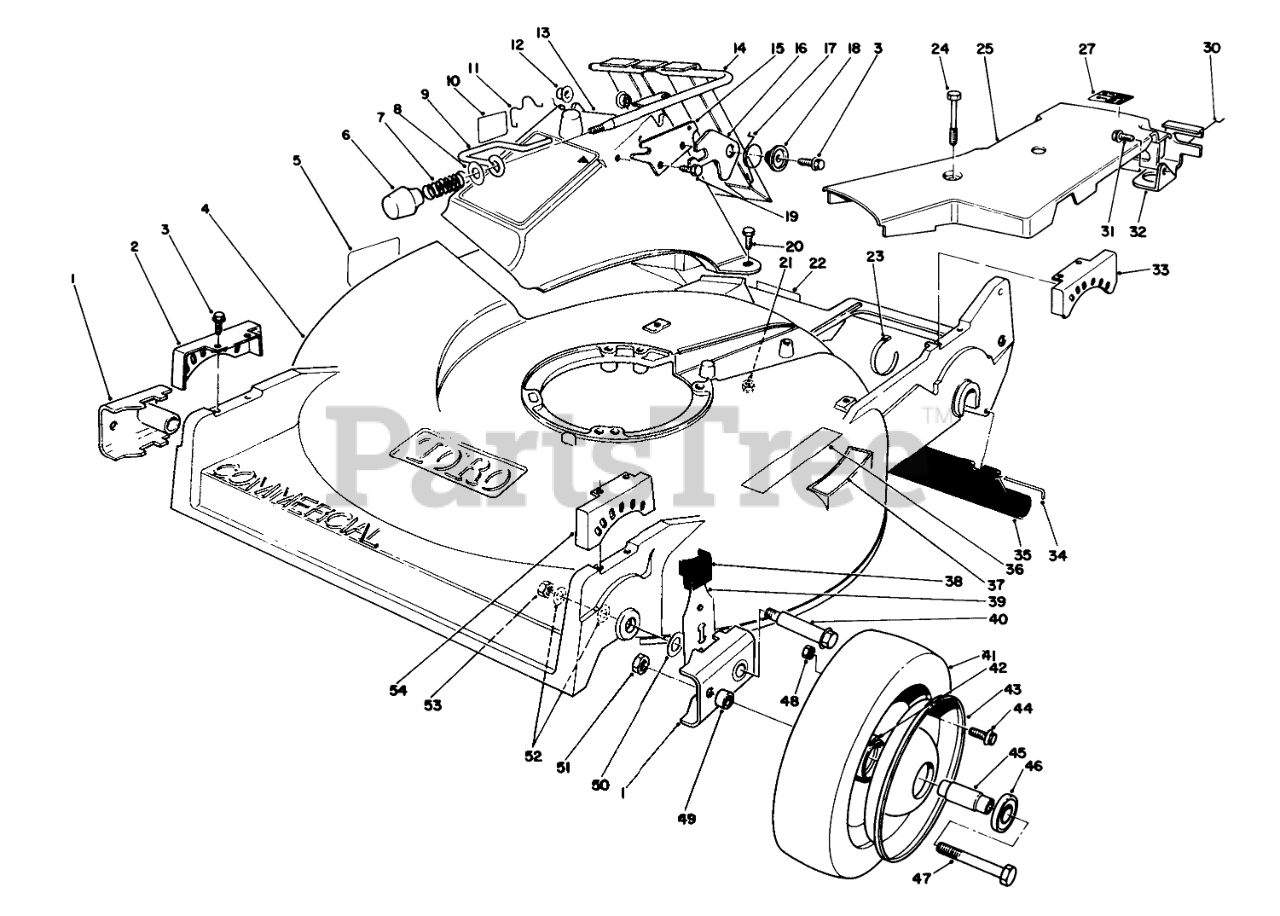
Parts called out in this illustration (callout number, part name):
1	ARM-PIVOT, FRONT
2	QUADRANT-FRONT, RH
3	SCREW-HWHTF
4	Housing-Commercial (Incl. Ref. #5 & 35)
5	Decal Danger
7	COMPRESSION SPRING
8	WASHER-FLAT
9	DOOR LATCH
10	DECAL - DANGER
11	DOOR RETAINER
12	BUSHING-NYLON
13	DISCHARGE CHUTE B
14	DOOR & HANDLE WA
15	DOOR LATCH PLATE
16	SAFETY LATCH
17	TORSION SPRING
18	DOOR SPACER
19	SCREW-HWH
20	SCREW-HH
21	NUT-LOCK, NI
22	Decal
23	TIE-CABLE
24	SCREW-HHFTF
25	Cover-Belt
27	Label-Grease
30	RETAINER-CABLE
31	SCREW-HWHTF
32	Bracket-Traction Adj.
33	QUADRANT-REAR, LH
34	ROD-SHIELD
35	SHIELD-TRAILING
36	Decal-Danger
37	DECAL - STEP PAD INT'L
38	KNOB-ARM
39	FRONT SPRING ARM ASM
40	WHEEL BOLT
42	HUB-BEARING
43	Wheel-Half
44	SCREW-HHF
45	SPACER-BEARING
46	BEARING-WHEEL
47	SCREW-HH
48	NUT-LOCK, NI
49	SPACER-WHEEL
50	WASHER-THRUST
51	NUT-LOCK, CONE
52	WASHER
53	Nut
54	QUADRANT-FRONT, LH
